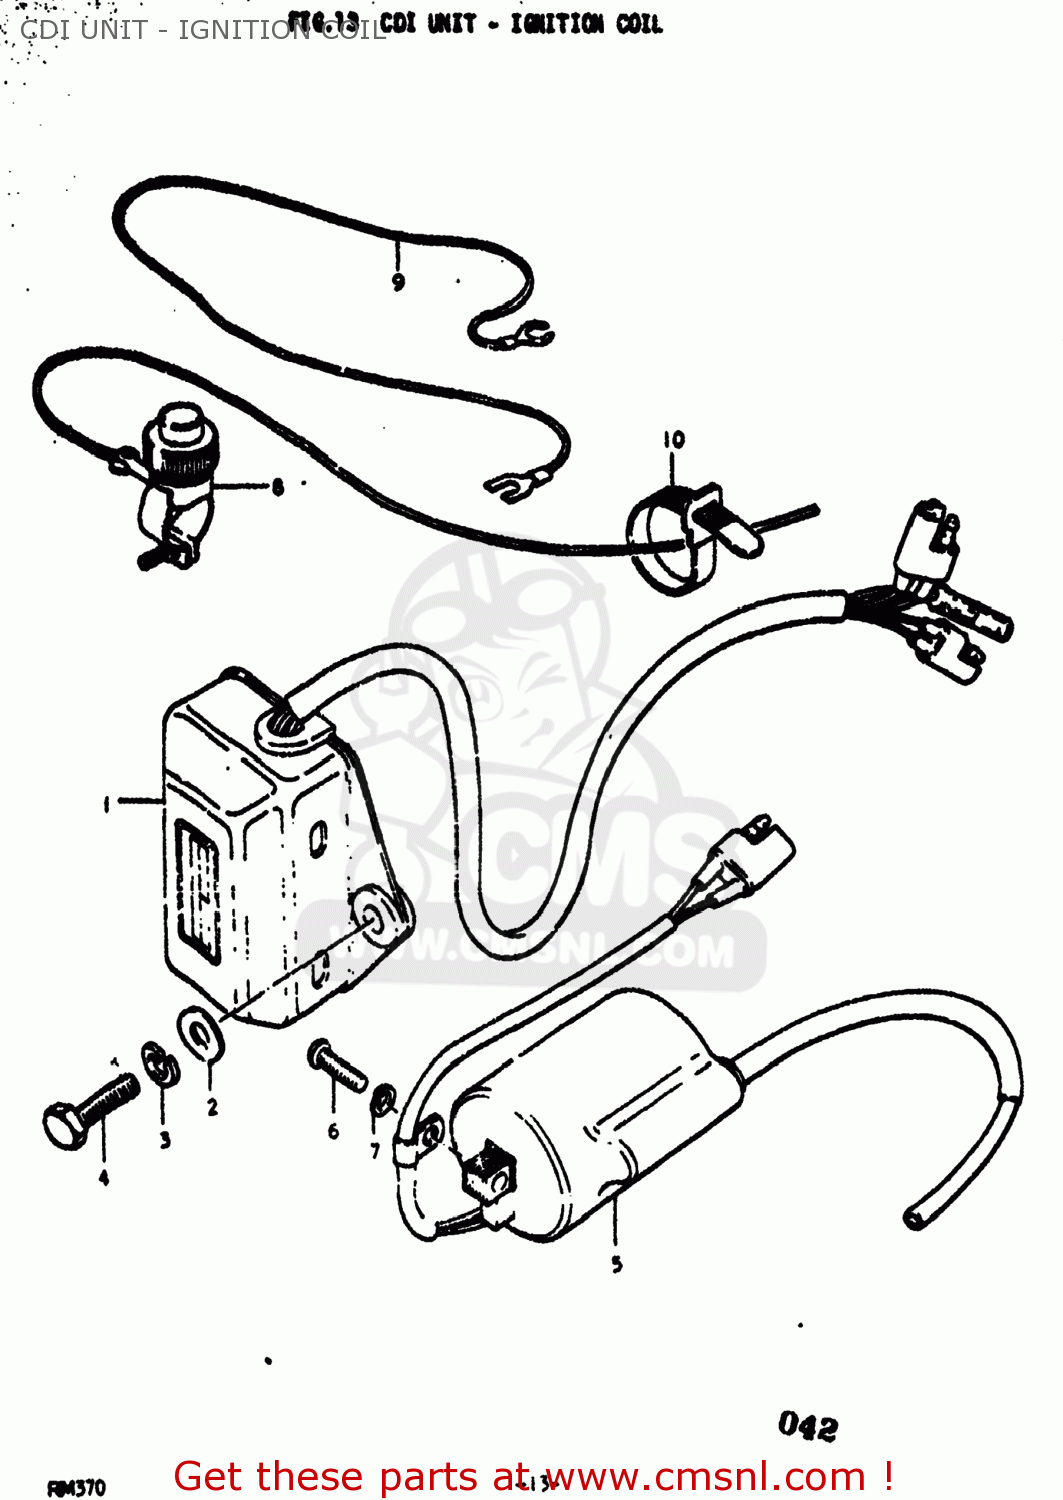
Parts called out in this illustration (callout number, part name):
1	CDI UNIT ASSEMBLY
2	WASHER(6.5X16X1.2)
3	LOCK WASHER
4	BOLT
5	COIL ASSY,IGNITION
6	SCREW
7	LOCK WASHER
8	SWITCH ASSEMBLY
9	WIRE,ENGINE STOP EARTH
10	CLAMP(L:120)
